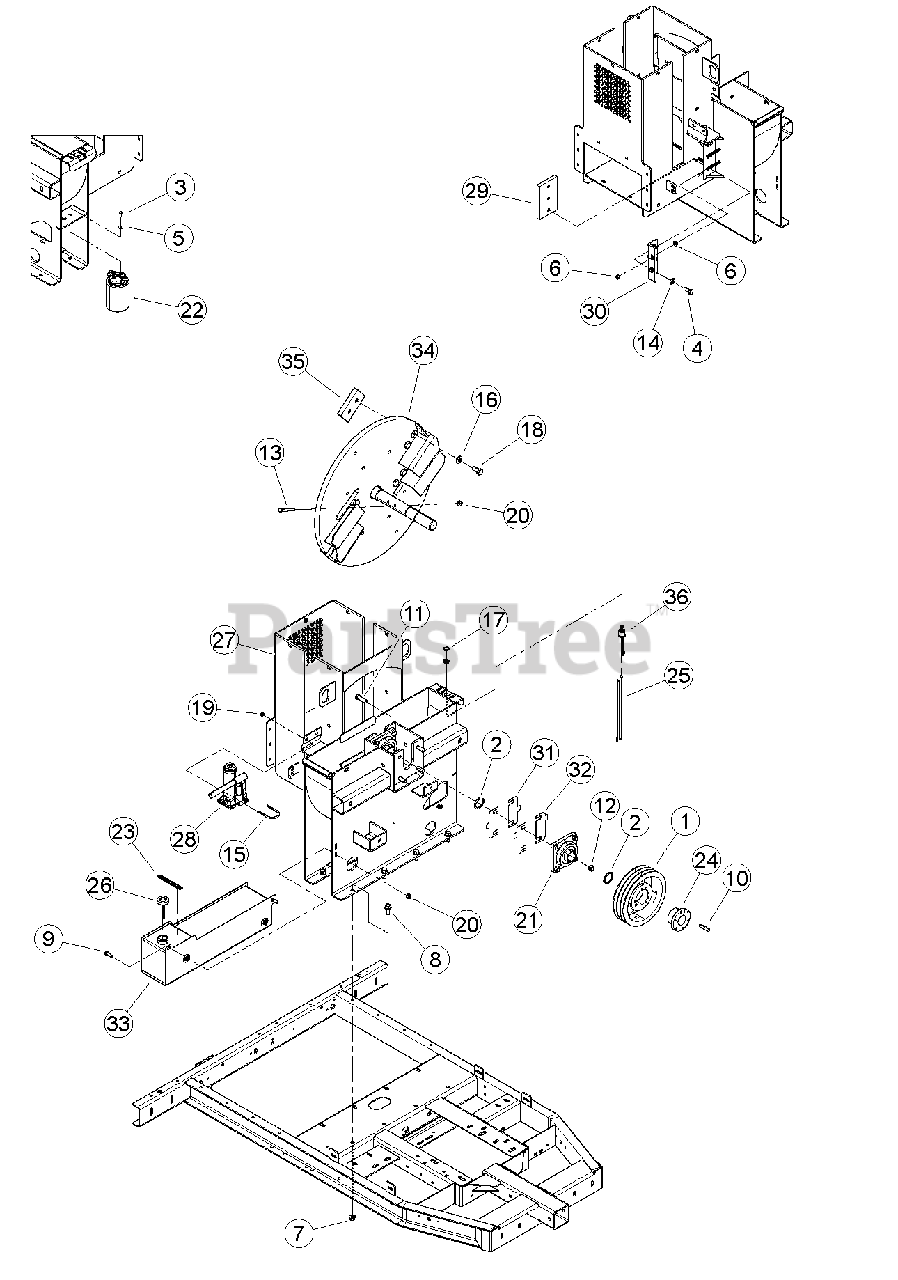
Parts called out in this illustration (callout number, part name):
1	SHEAVE, 3BQ9.4 SK
2	RING, 1-3/4 EXT HEAVY DUTY SNAP
3	BOLT, 1/4 X 3/4 GR5 HEX HD ZP
4	BOLT, 1/2 X 1-1/4" GR5 HHCS NC ZP
5	WASHER, 1/4" FLAT ZP
6	NUT, 3/8" SERRATED FLANGE NC ZP
7	NUT, 1/2-13 NYLOCK FLANGE
8	BOLT, 1/2 -13 X 1-1/4 FLANGE NC
9	BOLT, 3/8 X 1-1/4" GR5 CRG NC ZP
10	KEY, 3/8" SQ X 2" LG PLAIN
11	BOLT, 9/16 X 1-3/4 HEX GR5 ZP
12	NUT, 9/16 CENTER LOCK GRB ZP
13	BOLT, 3/8 X 3-1/2 FULL THD ZP GR5
14	WASHER, 1/2 HI-STRENGTH SAE ZP
15	U-BOLT, 1/4 X 1-1/2 PIPE
16	WASHER, 5/8 SAE HARDENED
17	NUT, 5/8-32 JAM
18	BOLT, M16 X 2.0 X 30 HEX HD W/PATCH
19	NUT, 1/4-20 NYLOCK-FLANGE
20	NUT, 3/8-16 NYLOCK FLANGE
21	BEARING, 1-3/4 4 BOLT FLANGE
22	ASSEMBLY, HYDRAULIC FILTER
23	DECAL, HYDRAULIC FLUID
24	BUSHING, SK 1-3/4"
25	WIRE ASSEMBLY, 37" FM SPADE AND RING
26	CAP, HYDRAULIC W/ DIPSTICK
27	WELDMENT, 6 IN CHIPPER HOUSING
28	JACK, HYDRAULIC 2 TON
29	ANVIL, 6" CHIPPER
30	WELDMENT, BLOCK ADJUSTOR
31	SHIM, 20 GA.
32	SHIM, 16 GA.
33	WELDMENT, HYDRAULIC TANK
34	WELDMENT, 6 CHIPPER ROTOR
35	KIT, CHIPPER BLADE
36	ASSEMBLY, SEALED SWITCH
